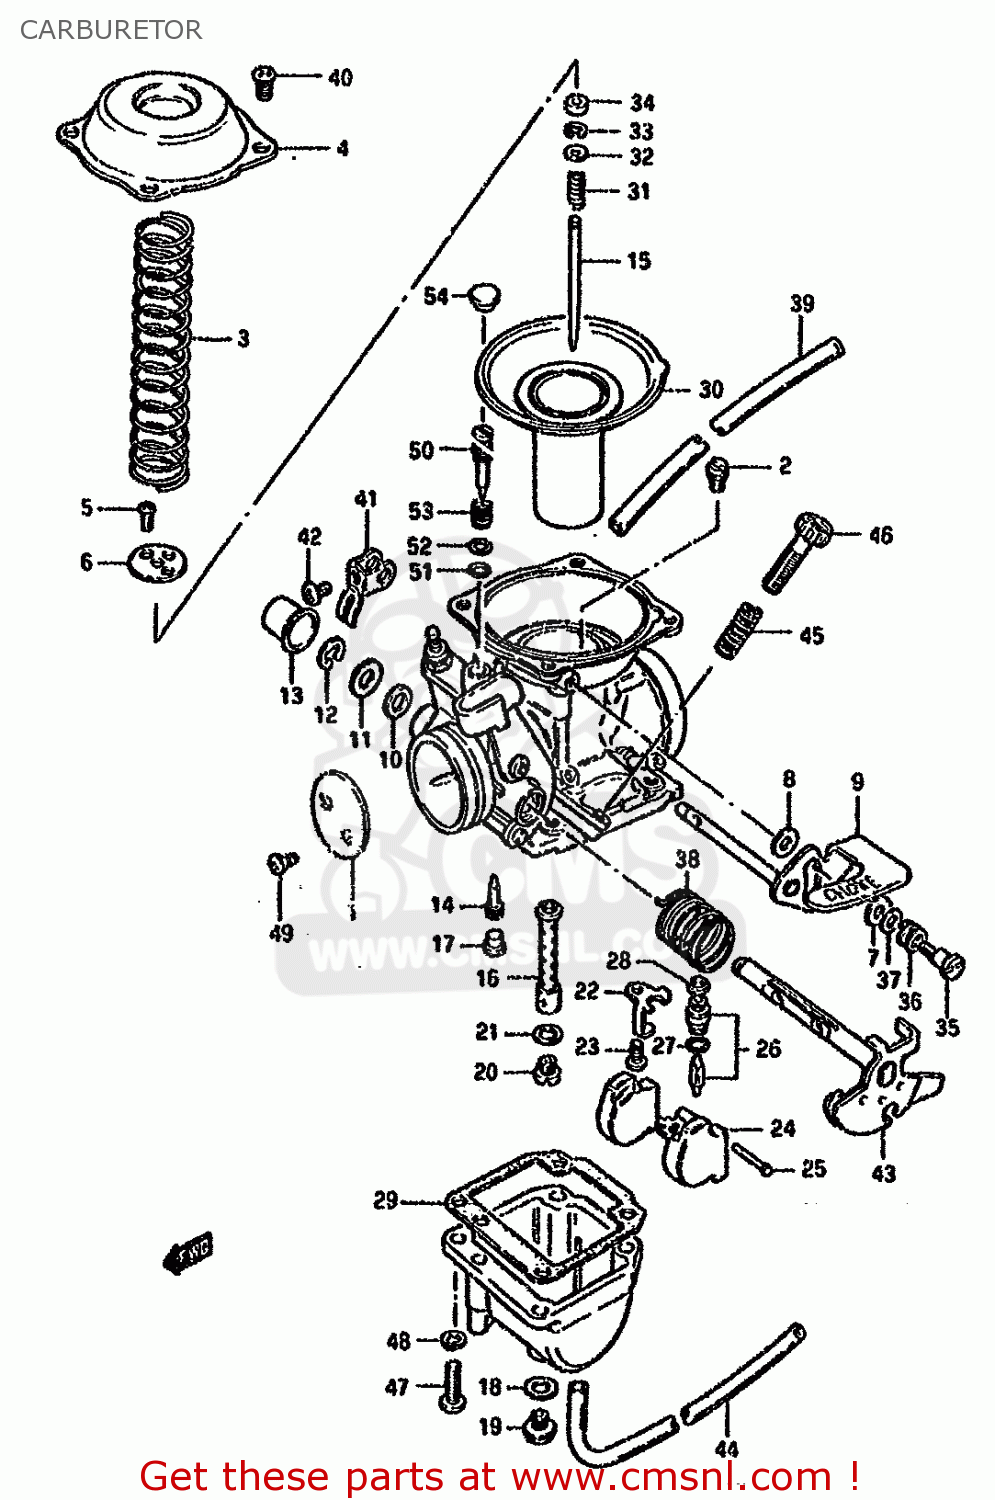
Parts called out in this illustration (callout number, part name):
1	VALVE,THROTTLE
2	JET,MAIN(180)
3	SPRING
4	COVER
5	SCREW
6	PLATE
7	PACKING (NAS)
8	WASHER,STARTER LEVER (4.1X12X0.8)
9	SHAFT ASSY,STARTER
10	SEAL
11	GASKET,THROTTLE SHAFT (NAS)
12	E RING
13	CAP
14	JET,PILOT(35)
15	NEEDLE,JET
16	JET,NEEDLE(P-2)
17	PLUG,NEEDLE JET
18	GASKET (NAS)
19	PLUG,DRAIN
20	JET,MAIN(102.5)
21	WASHER,NEEDLE NOZZLE
22	PLATE
23	SCREW
24	FLOAT
25	PIN,FLOAT
26	VALVE ASSY,NEEDLE
27	O-RING,NEEDLE VALVE
28	FILTER
29	GASKET,FLOAT CHAMBER (NAS)
30	DIAPHRAGM ASSEMBLY
31	SPRING
32	WASHER
33	CLIP
34	RING
35	SCREW
36	SPRING
37	WASHER,STARTER SHAFT
38	SPRING,THROTTLE SHAFT
39	HOSE
40	SCREW
41	LEVER
42	SCREW
43	SHAFT,THROTTLE
44	HOSE
45	SPRING,THROTTLE SCREW
46	SCREW,THROTTLE STOP
47	SCREW
48	LOCK WASHER
49	SCREW
50	SCREW,PILOT
51	O RING,PILOT AIR SCREW
52	WASHER
53	SPRING
54	PLUG
